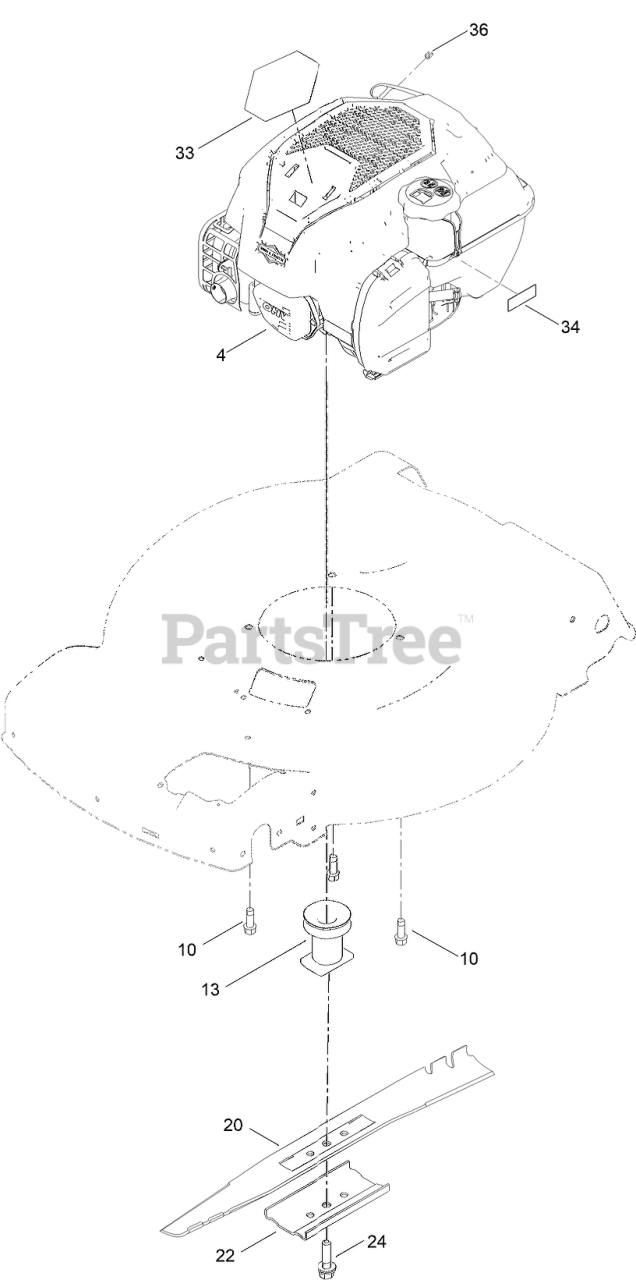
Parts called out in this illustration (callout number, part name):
10	SCREW-TAPTITE
13	DRIVER-BLADE
22	SUPPORT-BLADE
24	BOLT-BLADE
33	DECAL - BRIGGS 675 EXI SS
34	DECAL-LEVEL, FUEL
36	STOP-ROPE
